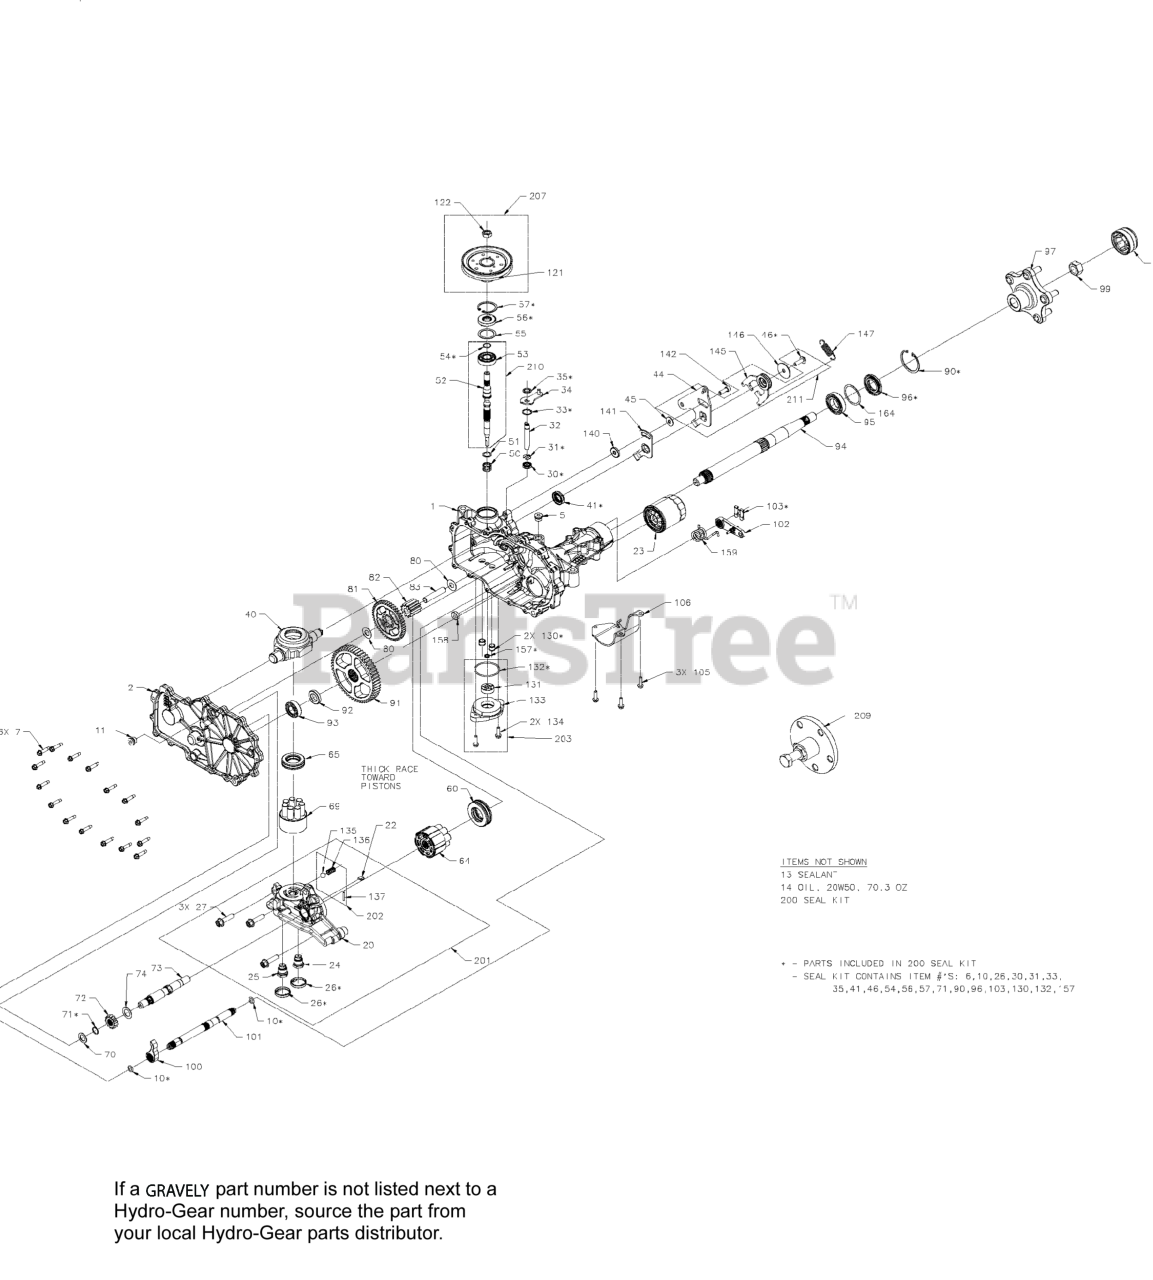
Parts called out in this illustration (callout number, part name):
1	KIT, HOUSING,MAIN,RH,CHRG,CNTL
2	KIT, COVER, SIDE, RH
5	PLUG, 9/16 18 METAL
7	SCREW,HEX WASHER 1/4-20X1.125
11	PLUG, 9/16 18 METAL
13	SEALANT TUBE 10.1OZ.
14	FLUID, HYDRO 15W50 QT
14	FLUID, HYDRO 20W50 QT
22	PLATE, BYPASS
23	FILTER, HYDRO-GEAR 2800 TRANS
26	SEAL, PLUG 1.375 X .250
27	HFHCS 3/8-16X1.5 (PATCH)
30	SEAL, LIP .375X.75X.25
31	RING. RETAINING
32	ROD, BYPASS
33	RING, RET .750
34	ARM, BYPASS
35	RING, RTNG .
40	TRUNNION, SWASHPLATE
41	SEAL, LIP 18X32X7
46	TWHCS 5/16-24 X 1.00
50	SPRING. BLOCK
51	WASHER. THRUST .59 X .79 X .04
55	WASHER 1.23X1.56X.04
56	SEAL, LIP 17X40X7
57	RING, RET 1.56 INT
60	HG THRUST BEARING (51462)
64	HG 16CC CYLINDER BLOCK (71579)
65	HG THRUST BLOCK (53502)
69	ASSY, BLOCK 7 PISTON
70	WASHER .63X1.0X.05
71	RING, RET 62 EXT
72	GEAR, 13T, STEEL
73	SHAFT, MOTOR
74	WASHER .71 X 1.16 X .04
80	WASHER .5X1.0X.032
82	GEAR 11 TOOTH STEEL
83	JACK SHAFT (PIN)
90	RING, RETAINING
91	GEAR, 54T
94	SHAFT, AXLE
96	SEAL, LIP 28 X 52 X 7 TC
97	HUB, HYDROGEAR P/N 71691
100	PAWL, BRAKE
101	SHAFT, BRAKE
102	KIT, BRAKE ARM
103	CLIP, RETAINING
106	GUARD, FILTER, RH
121	PULLEY, 4.5 INCH
122	NUT,HEX LOCK 1/2-20 NYLON INSERT
130	TUBE, CONNECTING
132	O-RING HYDROGEAR 52250
133	COVER, CHARGE PUMP
141	ARM, NEUTRAL RIGHT
142	SHCS 5/16-24X1 PATCH
147	SPRING, HYDROGEAR P/N 51833
157	SEAL, LIP 8 X 12 X 3 VC
158	MAGNET, RING
159	SPRING, TORSION CCW
164	WASHER, 1.355 x 2.035 x .021 FLAT
200	KIT, SEAL
201	KIT, CENTER SECTION, RH, CHRG
202	KIT CHARGE RELIEF
203	KIT, CHARGE PUMP
209	HUB PULLER 5 BLT
210	INPUT SHAFT HG 71978
211	RTN KIT HYDROGEAR P/N 71597
